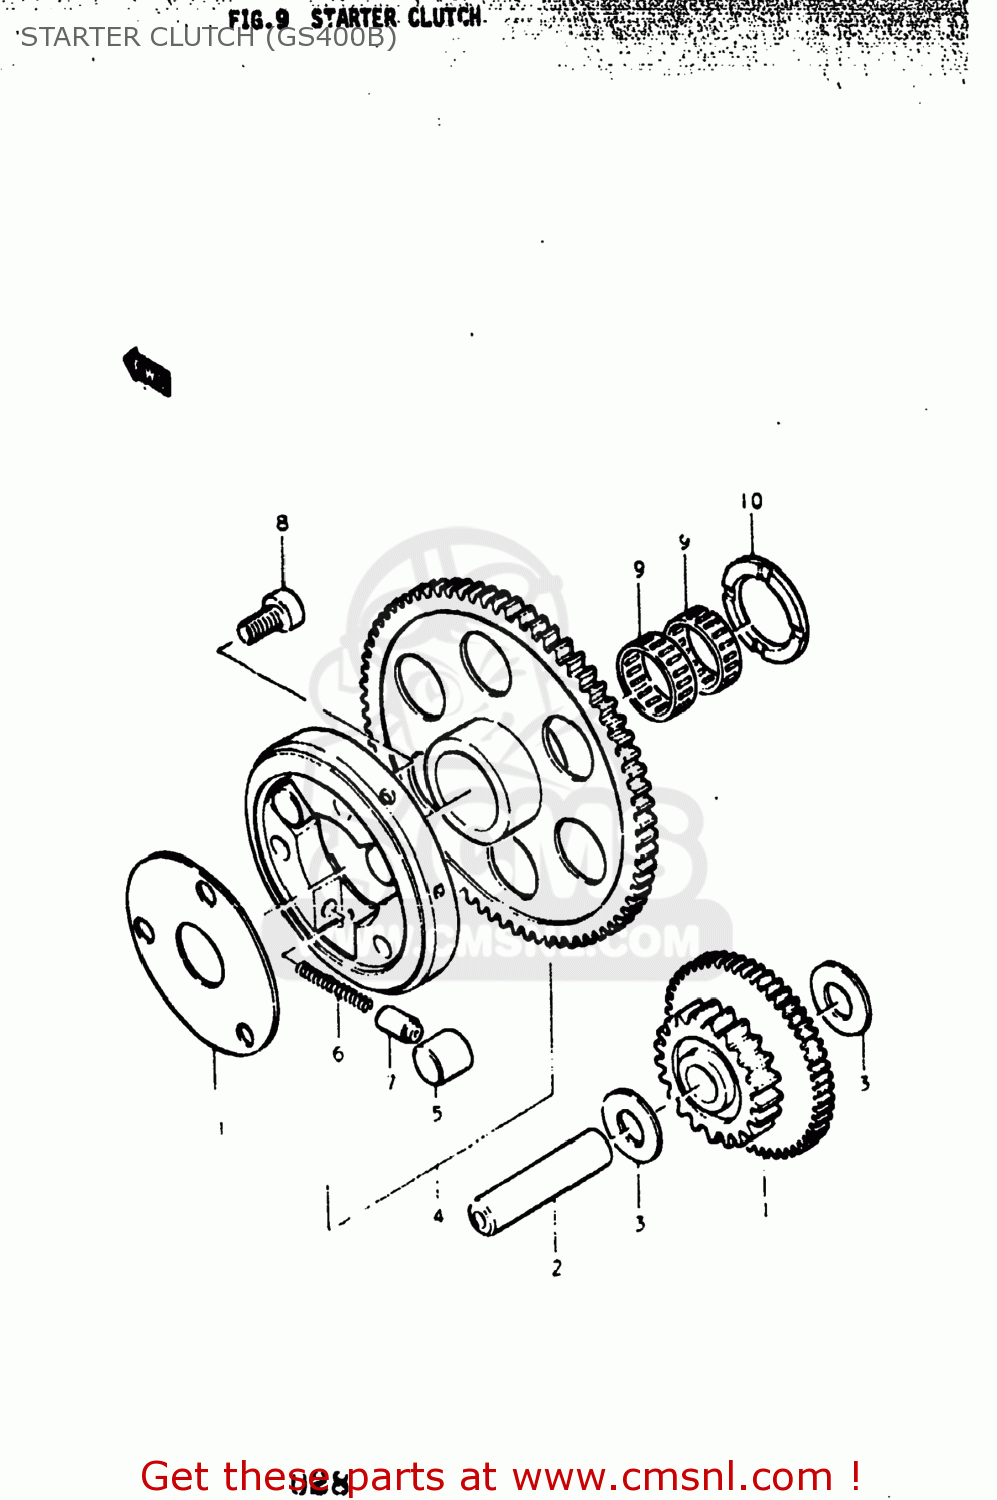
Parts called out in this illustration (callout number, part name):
1	GEAR,STARTER IDLER
2	PIN(7.4X13X56)
3	WASHER(13.3X25X0.85)
4	CLUTCH SET,STARTER
5	ROLLER(15X13)
6	SPRING
7	PIECE,PUSH
8	BOLT
9	BEARING(25X29X9.9)
10	WASHER(25X38X2.5)
11	SHIM,STARTER CLUTCH HUB
